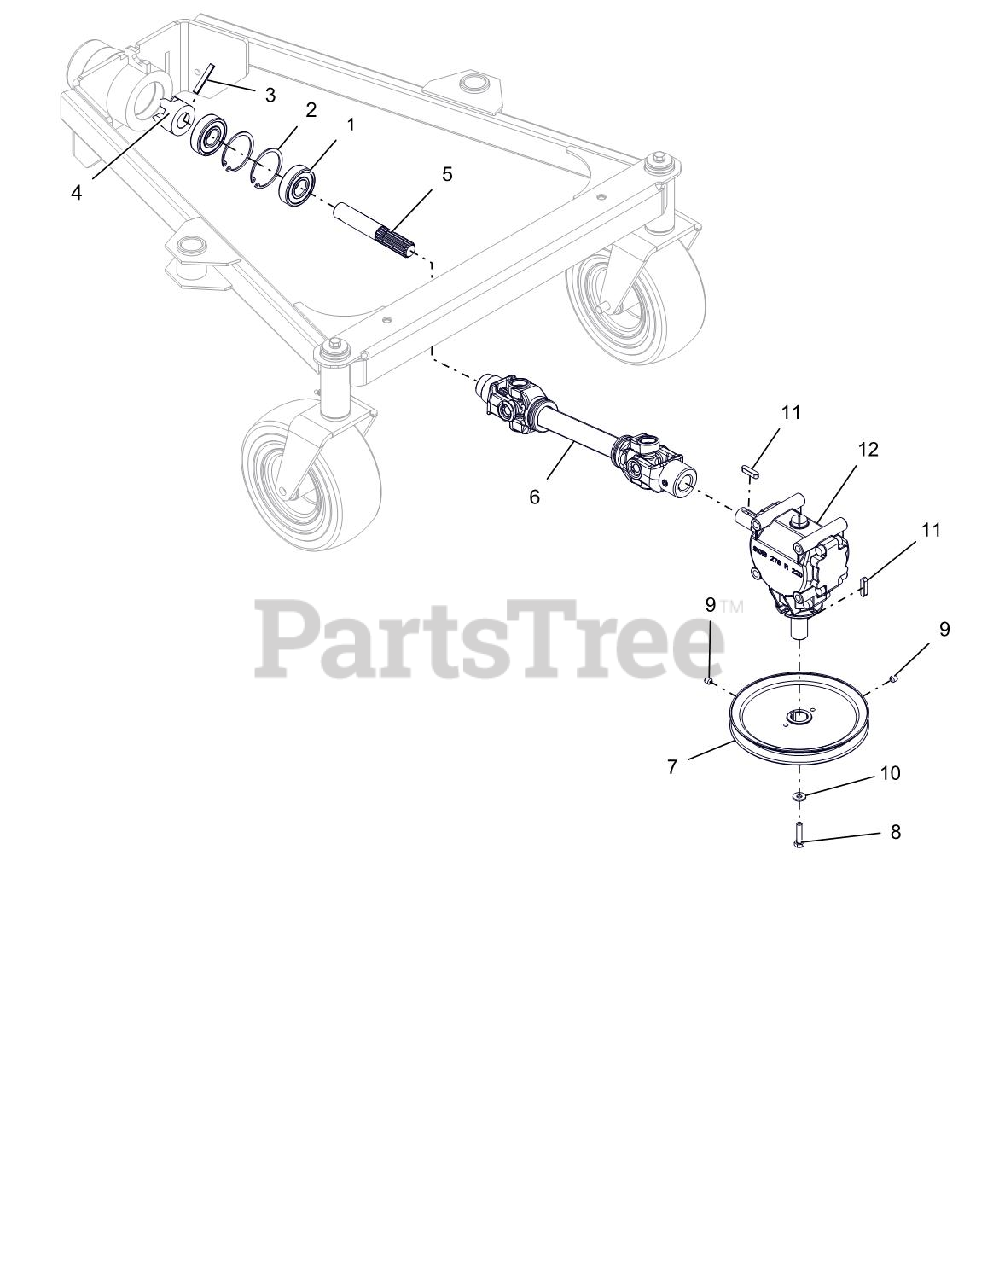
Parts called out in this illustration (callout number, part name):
1	BEARING, 6305LLC
2	RG-RTNG-INT 2.438X.078
3	PIN-ROLL 8MM X 50MM
4	CLAW COUPLING
5	PTO SHAFT
6	DRIVELINE,2-WHEEL FINISH MOWER
7	WLDMT, PULLEY 8.25
8	BLT, HEX M8-1.25X35 GR8.8ZC120
9	SET SCREW, 3/8-24 X 3/8 (CUP)
10	WSHR,BLVL M8X19.84X2.5 ZCMCH
11	KEY-STR 8X7X32MM ROUND ENDS
12	GEARBOX, RH 2.78:1
